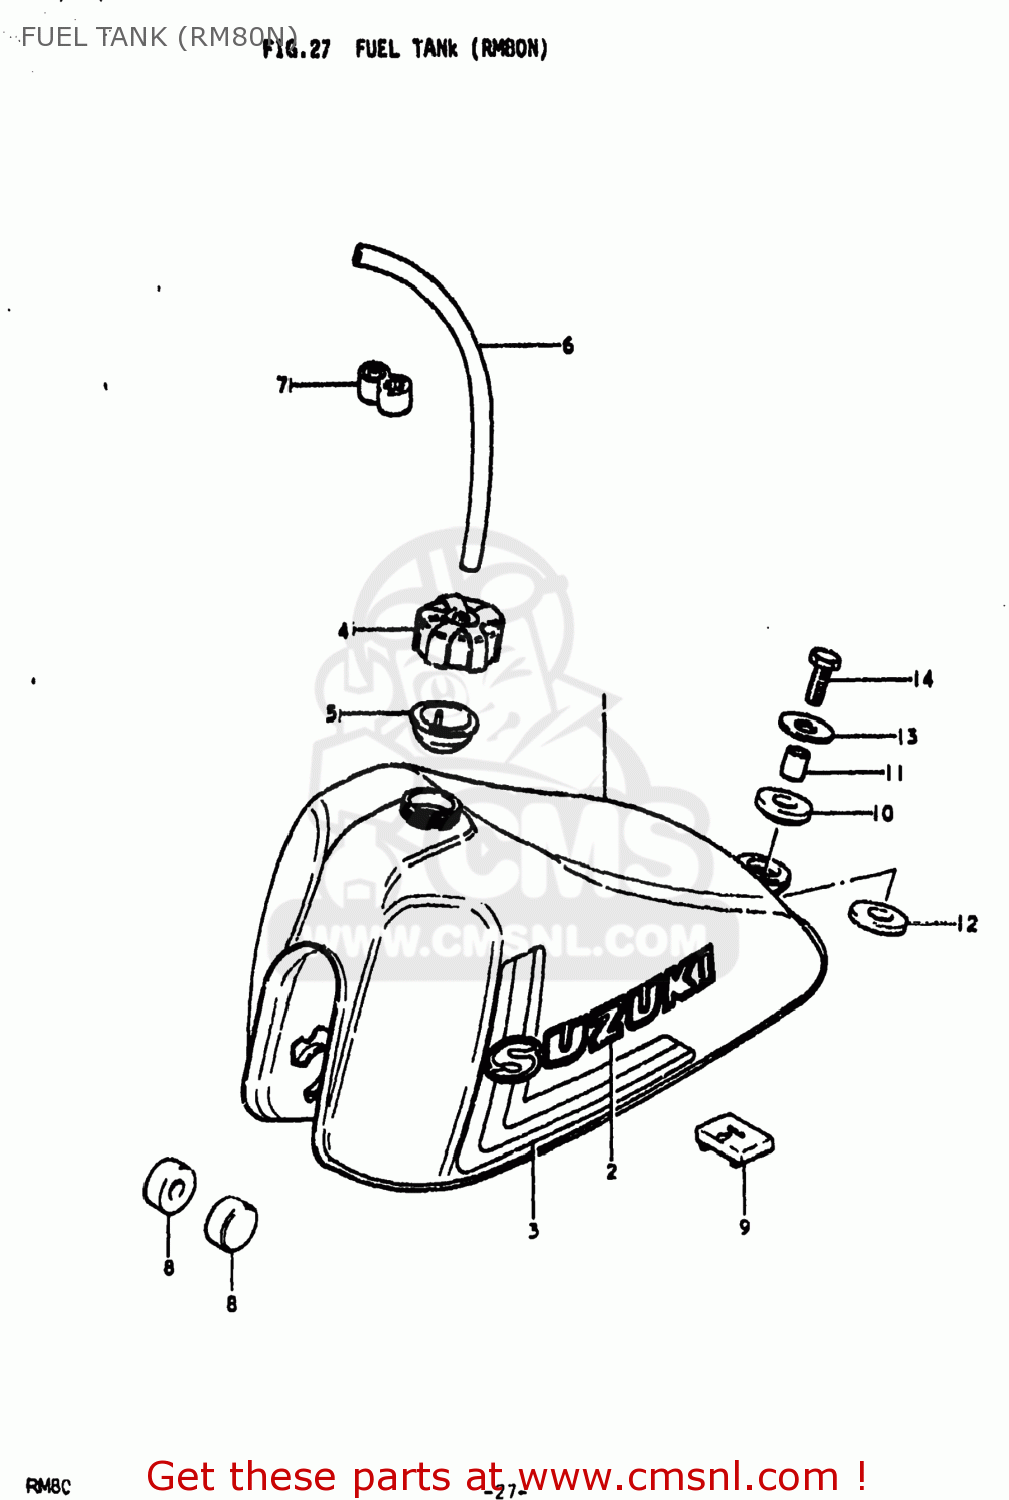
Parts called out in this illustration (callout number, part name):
1	TANK ASSEMBLY,FUEL
2	EMBLEM
3	TAPE SET
4	CAP ASSEMBLY,FUEL TANK
5	GASKET,FUEL TANK CAP
6	HOSE
7	CLAMP,FUEL TANK BREATHER HOSE
8	CUSHION
9	CUSHION,FUEL TANK
10	CUSHION
11	SPACER (8.8X12X13.5)
12	CUSHION
13	WASHER (8.5X29X1.6)
14	BOLT
